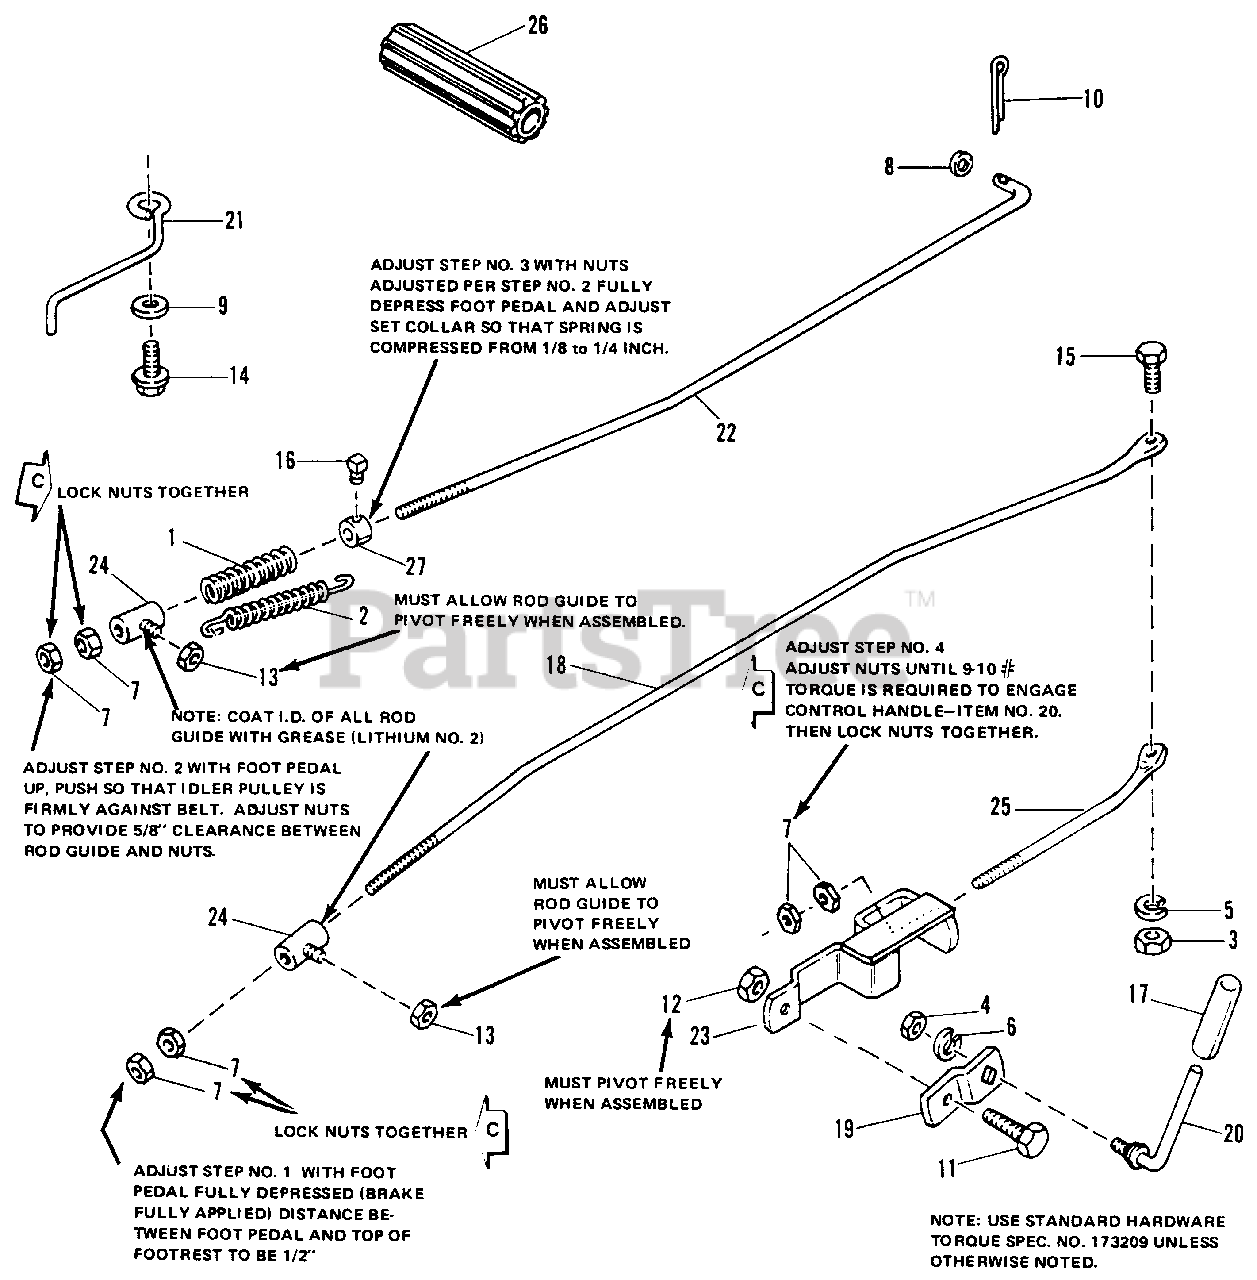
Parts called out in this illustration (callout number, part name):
1	SPRING, Compression
2	SPRING, Return
3	NUT, Hex, Full, 1/4-20
4	NUT, Hex, Full, 3/8-16
5	LOCKWASHER, 1/4
6	LOCKWASHER, 3/8
7	NUT, Hex, Full, 5/16-18
8	WASHER, Plain, 1/4
9	WASHER, Plain, 5/16
10	PIN, Cotter, 3/32 x 3/4
11	CAPSCREW, Hex Hd.,1/4-20 x 3/4
12	LOCKNUT, Hex, Full, 1/4-20
13	LOCKNUT, Hex, Full, 5/16-18
14	SCREW, Hex, Washer Hd., 5/16-18 x 7/8
15	CAPSCREW, Hex, 1/4-20 x 3/4
16	SCREW, Sq. Hd., Cup Pt. 1/4-20 x 3/8
17	GRIP
18	ROD, Brake
19	ARM, Pivot
20	HANDLE, Control
21	STOP, Belt
22	ROD, Clutch
24	GUIDE ASSEMBLY, ROD
26	COVER, Pedal
27	COLLAR, Set
